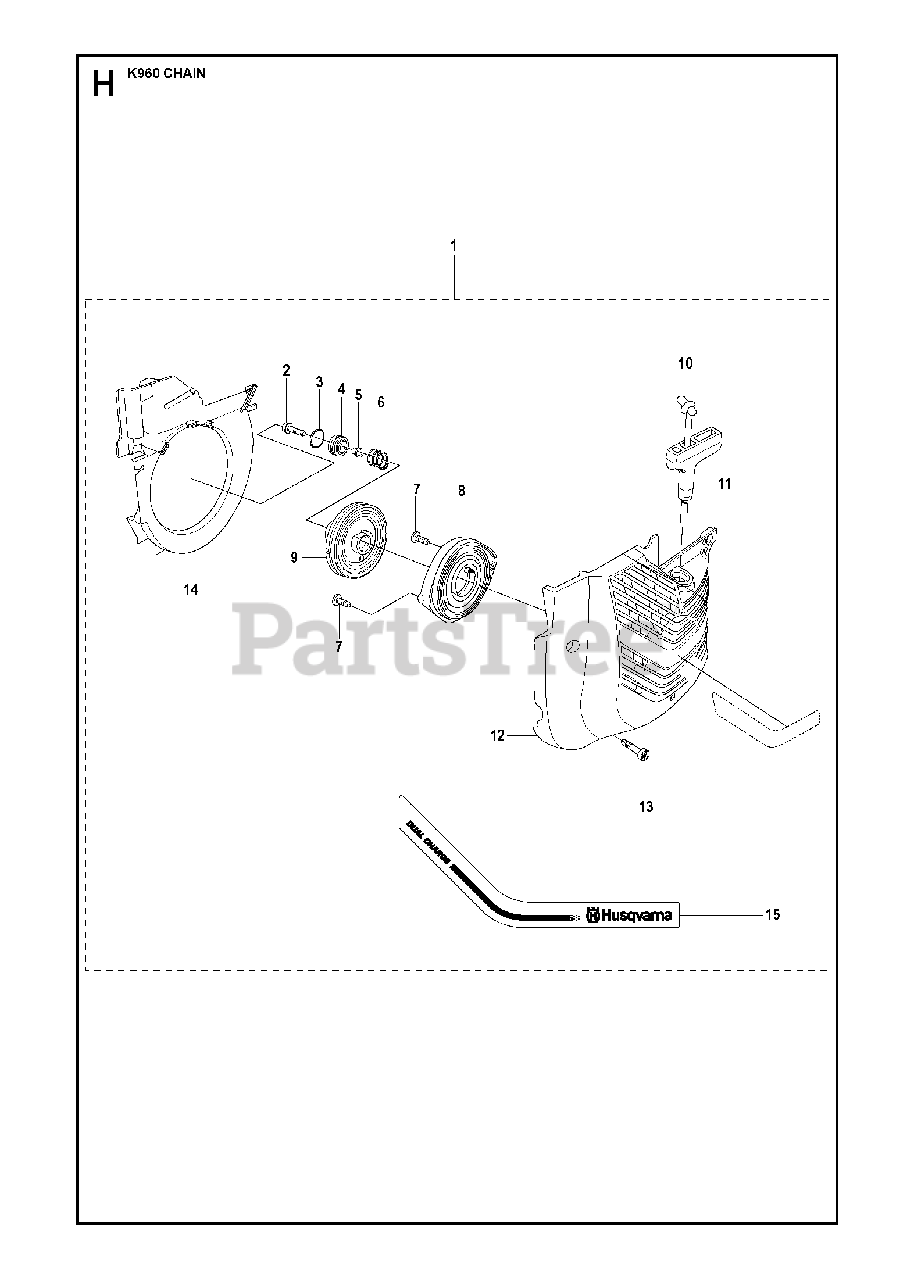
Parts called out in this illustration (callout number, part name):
1	STARTERIncl. 2 - 15
2	SCREW IHSCT
4	GROMMET
5	SPACING SLEEVE
6	COMPRESSION SPRING
7	SCREW CCRPANT
8	RECOIL SPRING
9	STARTER PULLEY
10	STARTER CORD50 m Coil
11	STARTER HANDLE
12	STARTER COVER
13	SCREW ITXSCM
14	AIR CONDUCTOR
